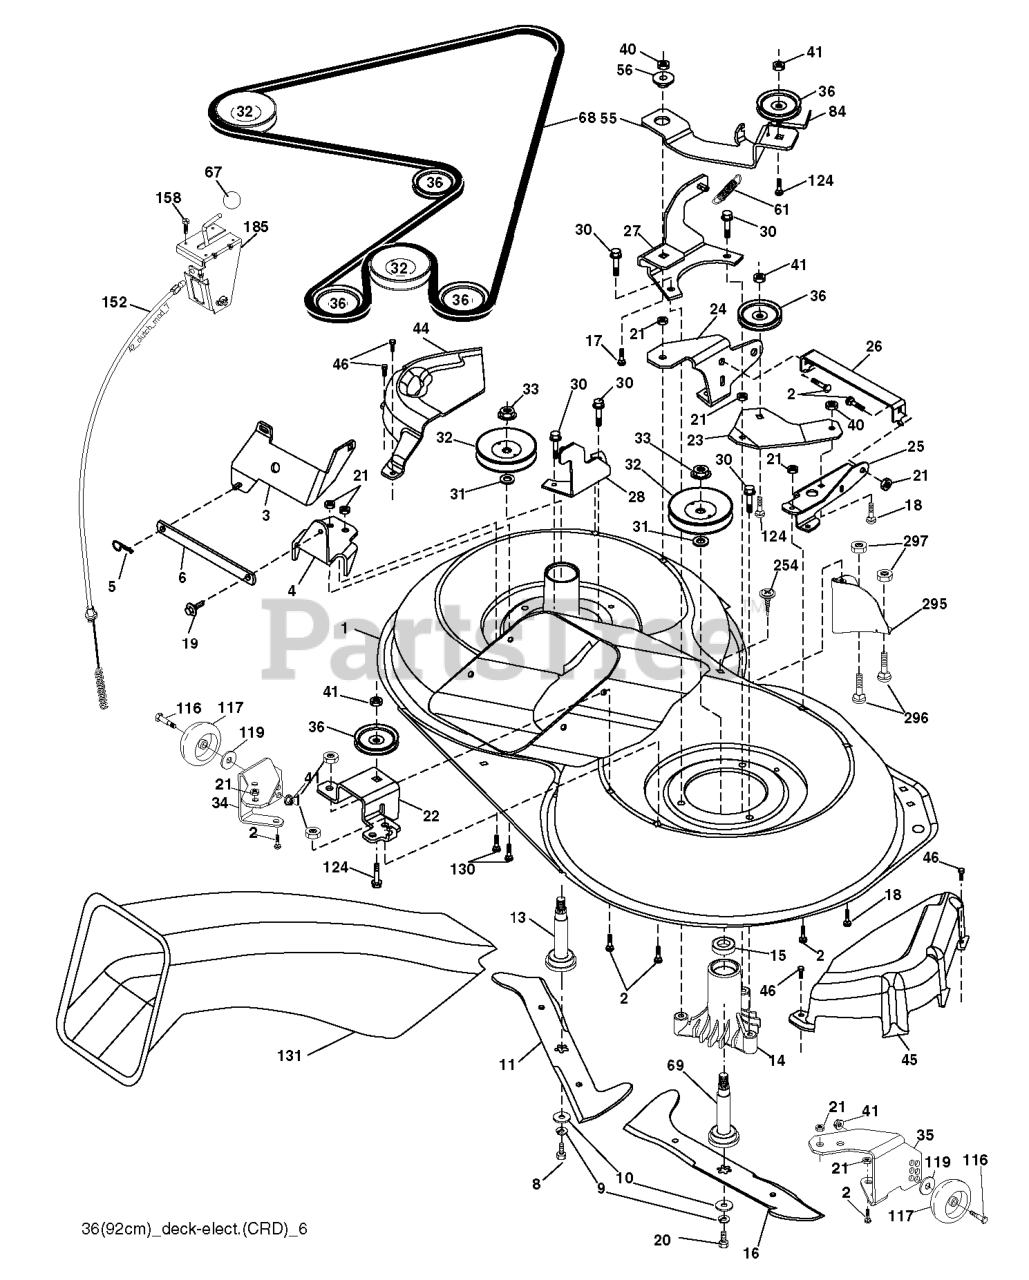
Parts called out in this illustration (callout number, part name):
2	RP BOLT 5/16-18 X3/4 ZN/YEL GR
5	RETAINER-SPRNG RB
6	BAR.SWAY.92.CRD
8	BOLT.3/8-24X1.25 GR8
9	LOCKWASHER
10	WASHER.BLADE
13	SHAFT ASM VENT
14	HOUSING.MANDREL.VENTED (MACHD)
17	BOLT.3/8-14X1.25
19	BOLT SHD 5/16-18
20	BOLT.3/8-24X1.25GR8. LHTHRD
21	LOCKNUT
26	SUPPORT
30	SCREW, WASHER HEAD
31	WASHER.SPACER.MANDREL
32	PULLEY MANDREL
33	NUT.FLANGE.LOCK.TOP
36	PULLEY.IDLER.4.25
41	NUT LOCK FLG 3/8-16 UNC
45	COVER.MANDREL.RH.CRD
46	SCREW.1/4-20X5/8
55	ARM.IDLER.92 CRD.2006
56	SPACER.RETAINER.MOWER
61	SPRING
67	KNOB T (3/8 HOLE)
68	BELT.DRIVE.92CM.CRD.2006
69	SHAFT.ASM.W/LWR.BRG.RH.THREAD
84	KEEPER, BELT IDLER
116	BOLT.SHOULDER.3/8-16X3-5/8.
117	RP WHEEL. GUAGE RALLY
119	WASHER
124	BOLT.3/8-16X1.50
130	BOLT.CARR.SQNK.5/16-18UNC.X3/4
131	CHUTE BAGGER
158	SCREW
185	HEAD ASM. CABLE CLUTCH
254	SCREW 3/8-16X1
296	BOLT
297	NUT CENTERLOCK
